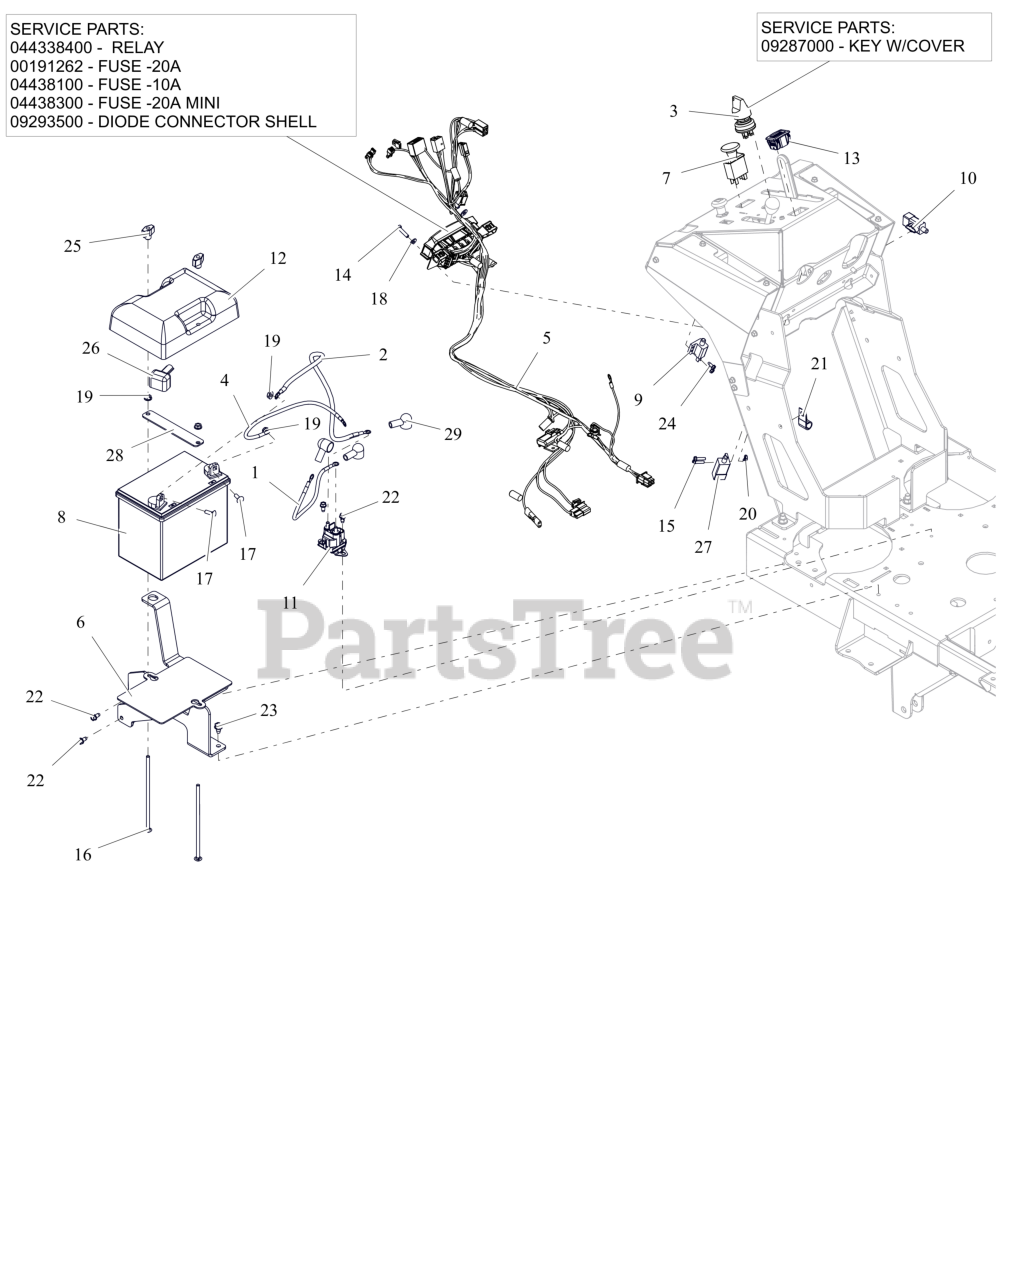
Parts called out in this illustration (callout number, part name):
1	CABLE-POSITIVE BATTERY 9.00"
2	CABLE - START 22.00"
3	SWITCH, IGNITION
3	KEY, W/ SHIELD
4	CBL,NEGATIVE BATTERY 20.00
5	HARNESS, 36-60 PRO-WALK
5	RELAY, MICRO5 WITH RESISTER
5	FUSE, 20 AMP BLADE S/O
5	FUSE,10 AMP MINI-ATC
5	FUSE,20 AMP MINI ATC
5	DIODE, CONNECTOR SHELL
6	WLDMT- BATTERY TRAY
7	SWITCH, CLUTCH
8	BATTERY, 300 CCA 10U1L
9	SWITCH- SINGLE POLE N.O.
10	SWITCH, SNAP IN - N.O./N.O.
11	SOLENOID, STARTER (SEALED)
12	COVER, BATTERY
13	HOUR METER
14	BLT, HEX M6-1.0 X 25 G8.8 ZCC
15	BLT, HWH #10-24X.75 ZCC
16	BLT,RHSN .25-20X7.00 G2 ZCC
17	BLT, RHSN .25-20X.750 G5 ZCC
18	WSHR,FLT .281X.625X.065 ZCC
19	NUT-SPNLK-FLG .25-20 ZC120
20	NUT, HEX .250-20 GR5 ZCC
22	SCR-TAP .25-20X.50 HWH ZCC
23	SCR,TAP .312-18X.50 HWH TR ZCC
24	SCR,TAP #10-24X.50 HWH TR ZCC
25	KNOB, WING - .25-20 UNC
26	INSULATOR
27	SWITCH,INTERLOCK
28	STRAP, BATTERY
29	BOOT, EYELET TERMINAL
